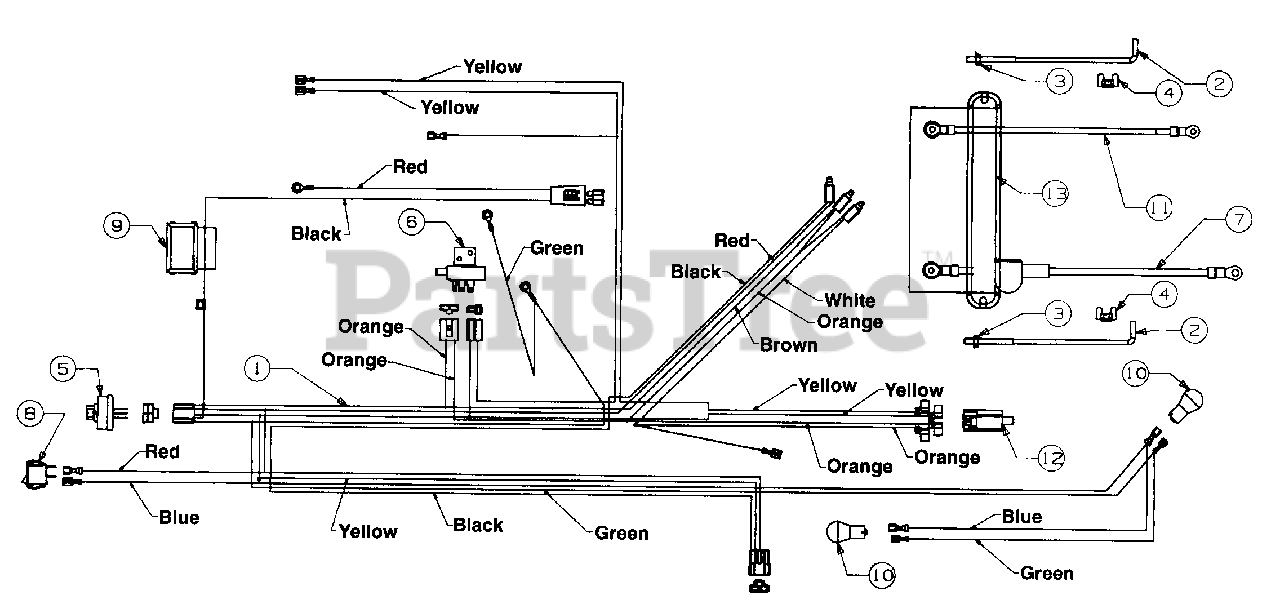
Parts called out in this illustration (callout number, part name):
1	Wire Harness
2	Battery Hold Down Rod
3	Hex L-Nut 1/4-20 Thd.
4	Wing Nut 1/4-20 Thd.
5	Ignition Switch
6	Safety Switch (PTO)
7	Wire w/Boot 14" Lg.
8	Light Switch
9	Ammeter
10	Bulb (Headlight)
11	Wire 12" Lg.
12	Safety Switch (Clutch)
13	Battery Cover
